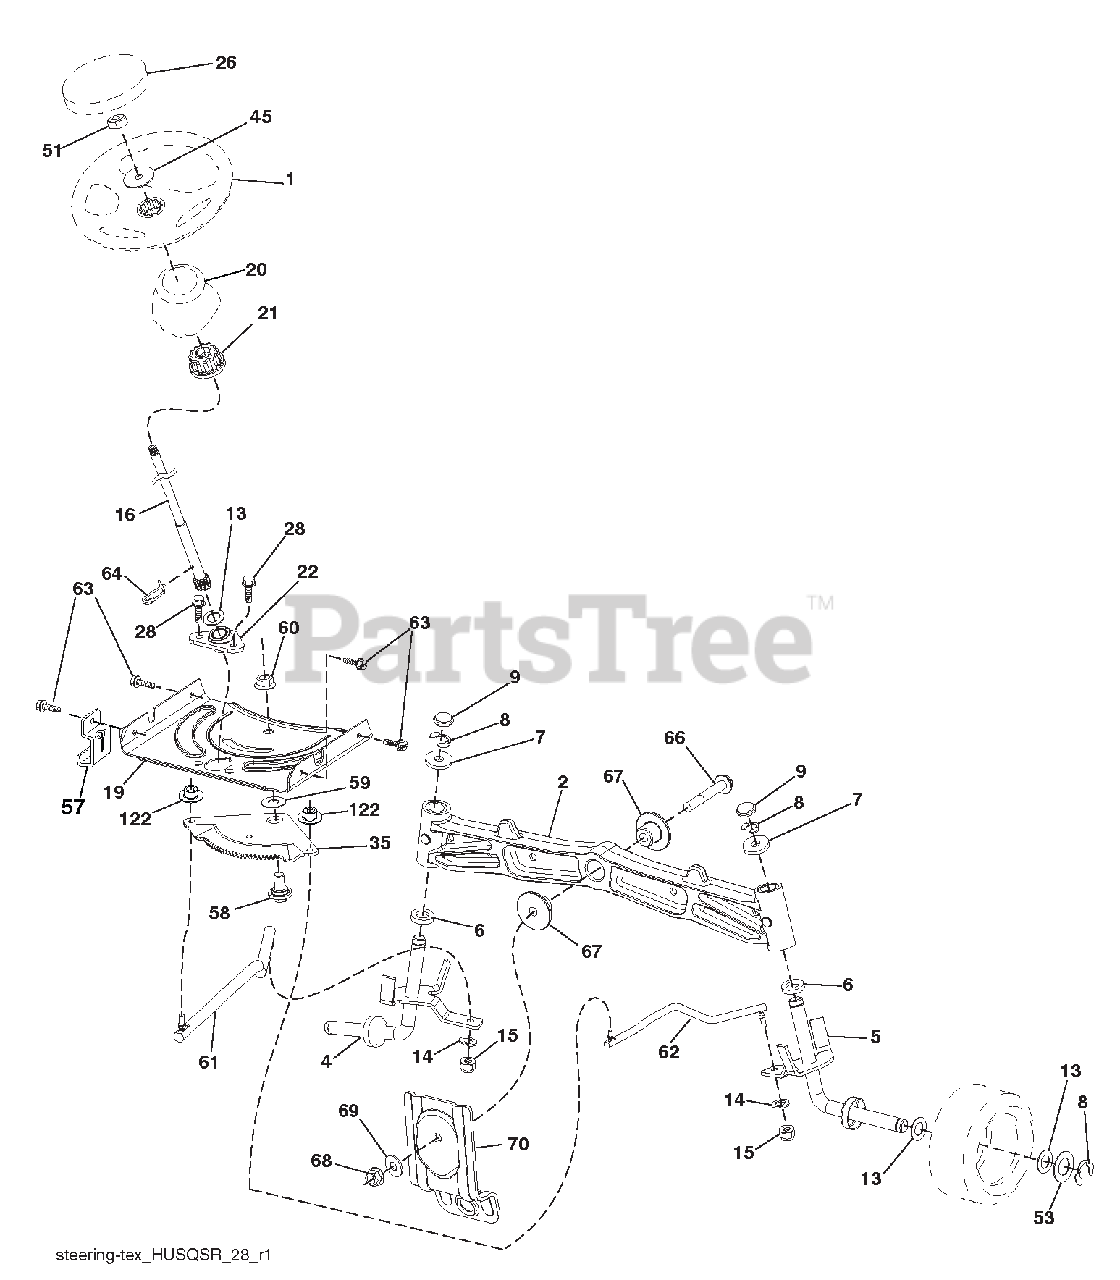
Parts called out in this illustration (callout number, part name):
1	WHEEL STEERING
2	AXLE.CAST IRON
4	SPINDLE.WELDED.LH.15"TEX
5	SPINDLE.WELDED.RH.15"TEX
6	WAHSER THRUST .75 X 1.230
7	WASHER.25/32 X 1-5/8 X 16GA.
8	RING.KLIP.#T5304-75
9	CAP.SPINDLE.FR.TOP.BLK.
13	WASHER.25/32 X 1 1/4 X 16 GA.
14	Washer, Lock 3/8
15	NUT.CROWNLOCK.3/8-24
16	SHAFT.STEER.3/4 TEX.NON-PLATED
19	PLATE.STEER.DDL.NLT/NGT
20	BOOT.STEERING
21	ADAPTER.WHEEL.STRG..760
22	STEERING SUPT. LOWER
26	CAP WHEEL STEERING HRS/SRS BLK
28	SCREW.HEXWSH THDR3/8-16X3/4.BL
35	GEAR SECTOR.PLATE.DDL.NLT/NGT
45	WASHER.9/16ID X 2-3/8OD.12GZIN
51	NUT.HEX.JAM.TOPLOCK.1/2-20 UNF
53	WASHER.HARDEN..793 X 1.637X060
57	BRACKET.UPSTOP.GT/LT.TEX
58	BOLT.SHOULDER.SECTOR.PIVOT.CFM
59	WASHER.THRUST.SECTOR.STEER.NLT
60	NUT.FLANGE LOCK.5/8-11
61	DRAGLINK.LH.BALLSTUD.DDL.
62	DRAGLINK.RH.BALLSTUD.DDL
63	SCREW.5/16-18X3/4.SMGML.TAP/BL
64	RETAINER.CLIP.SPRING.STEERING
66	BOLT.HEX.FGHD.7/16-14 X 3.SERR
67	BUSHING.PM.FRONT AXLE
68	NUT.LOCK.FLANGE.7/16-14.GR5
69	WASHER.1.5 X .505 X .118
70	BRACKET.DECK.SUSPENSION.FRONT
122	CAP GEAR SECTOR
